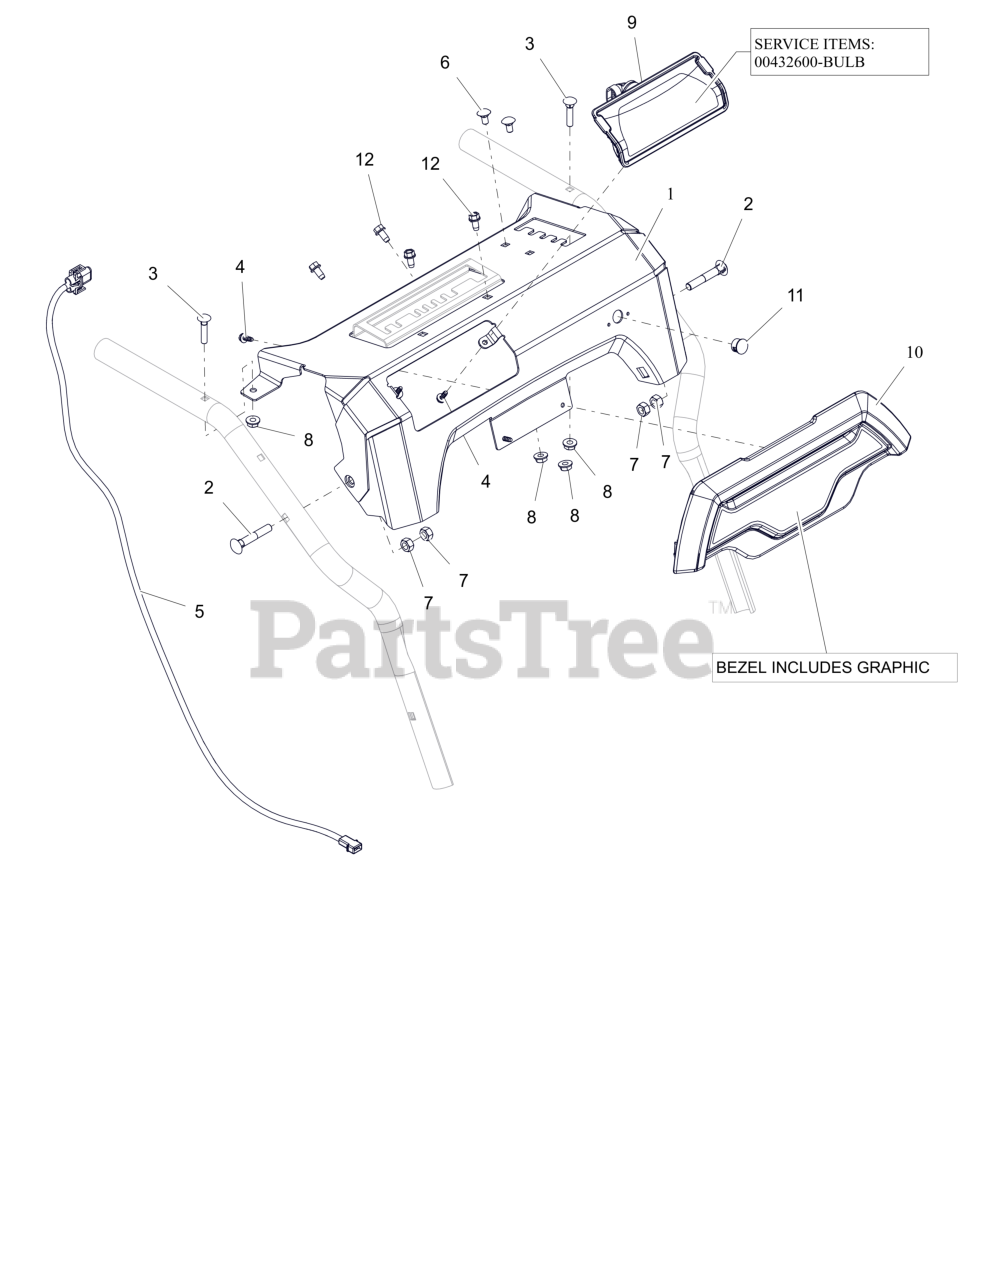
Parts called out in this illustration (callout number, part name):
1	PANEL, DASH - COMPACT
2	BLT-RDHDXLSQNK .31-18X2.0 G5YZ
3	BLT-RDHDXLSQNK.25-20X1.25 G5ZC
4	SCR, PLASTIC #10X.50
5	HARNESS, LIGHT - COMPACT
6	BLT, RHSN .25-20X.500 G5 ZCC
7	NUT,LK-CTR .31-18 GA ZCC
8	NUT-LK-CTR-FLG .25-20 ZC120
9	HEADLIGHT ASY, HALO 20W 2SHOT
9	BULB, LIGHT-HALOGEN 20W
10	BEZEL, SMALL - COMPACT
11	HOLE PLUG, PLASTIC .56 HOLE
12	SCR-TAP .25-20X.50 HWH ZCC
